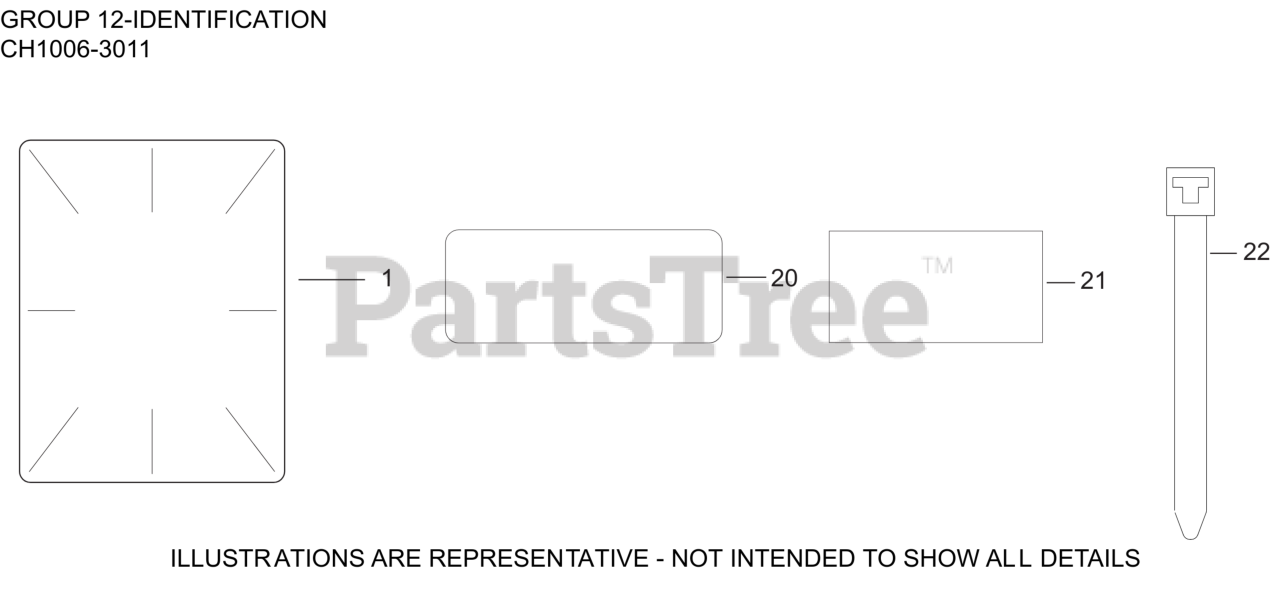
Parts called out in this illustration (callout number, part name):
1	LABEL, CLEAR LAMINATION
20	DECAL, SYNTHETIC OIL
21	DECAL, USA
